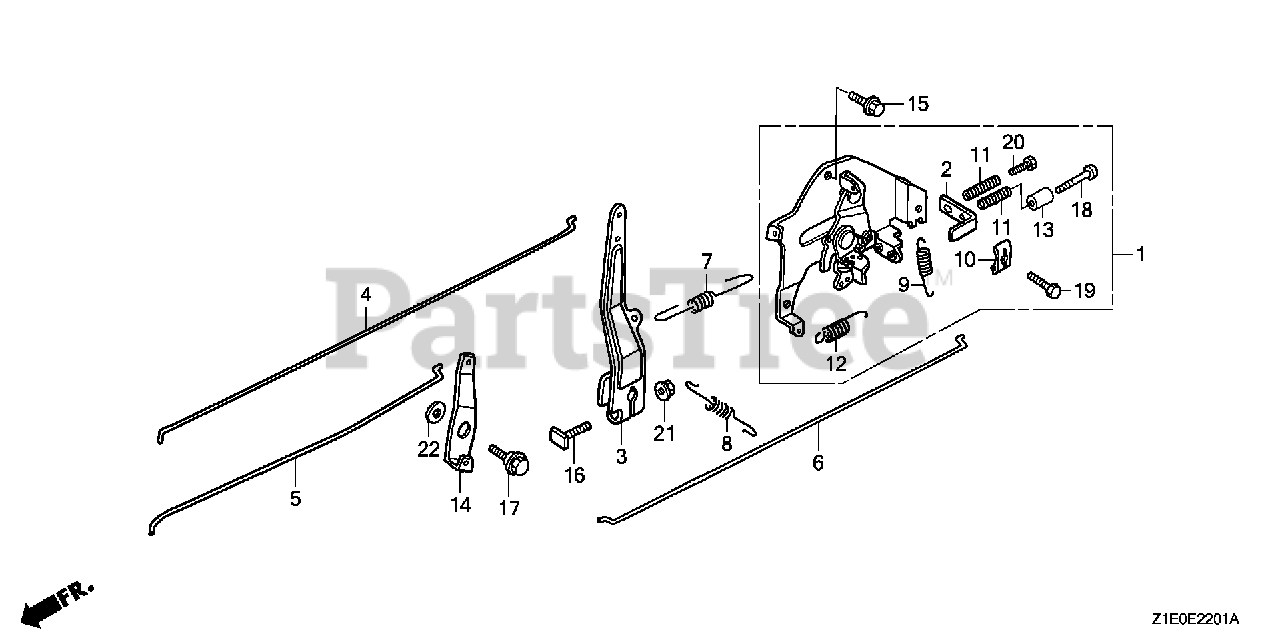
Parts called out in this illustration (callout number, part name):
1	CONTROL ASSY.
2	PLATE, SCREW ADJUST GUARD
3	ARM, GOVERNOR
4	ROD, GOVERNOR
5	ROD, CHOKE
6	ROD, JOINT
7	SPRING, GOVERNOR
8	SPRING, GOVERNOR PRIMARY
9	SPRING, LEVER
10	HOLDER, CABLE
11	SPRING, CONTROL ADJUSTING Use from Engine SN 2327377.
12	SPRING, CABLE RETURN
13	COLLAR, STOPPER
14	LEVER, CHOKE JOINT
15	BOLT, FLANGE (6X12) (CT200)
16	BOLT, GOVERNOR ARM
17	BOLT, FLANGE (6MM)
18	SCREW, RECESSED (5X35)
19	BOLT, RECESSED (5X16)
20	BOLT, RECESSED (5X22)
21	NUT, FLANGE (6MM)
22	WASHER, PLAIN (6MM)
